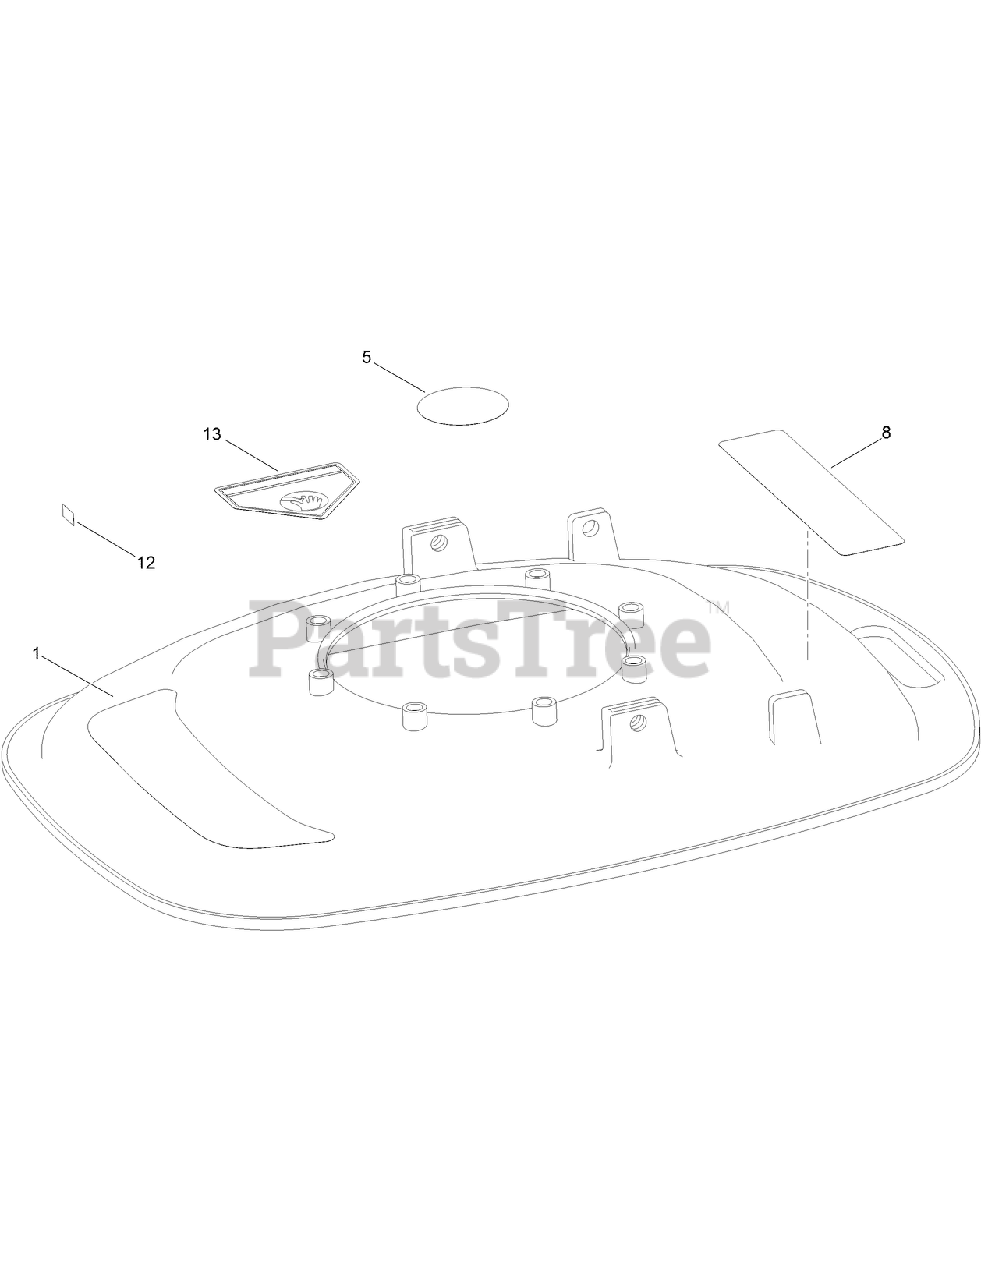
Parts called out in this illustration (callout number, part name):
1	DECAL-HOVER PRO
5	DECAL-ENGINE
8	DECAL-WARNING
12	DECAL-STOP
13	DECAL-DANGER
